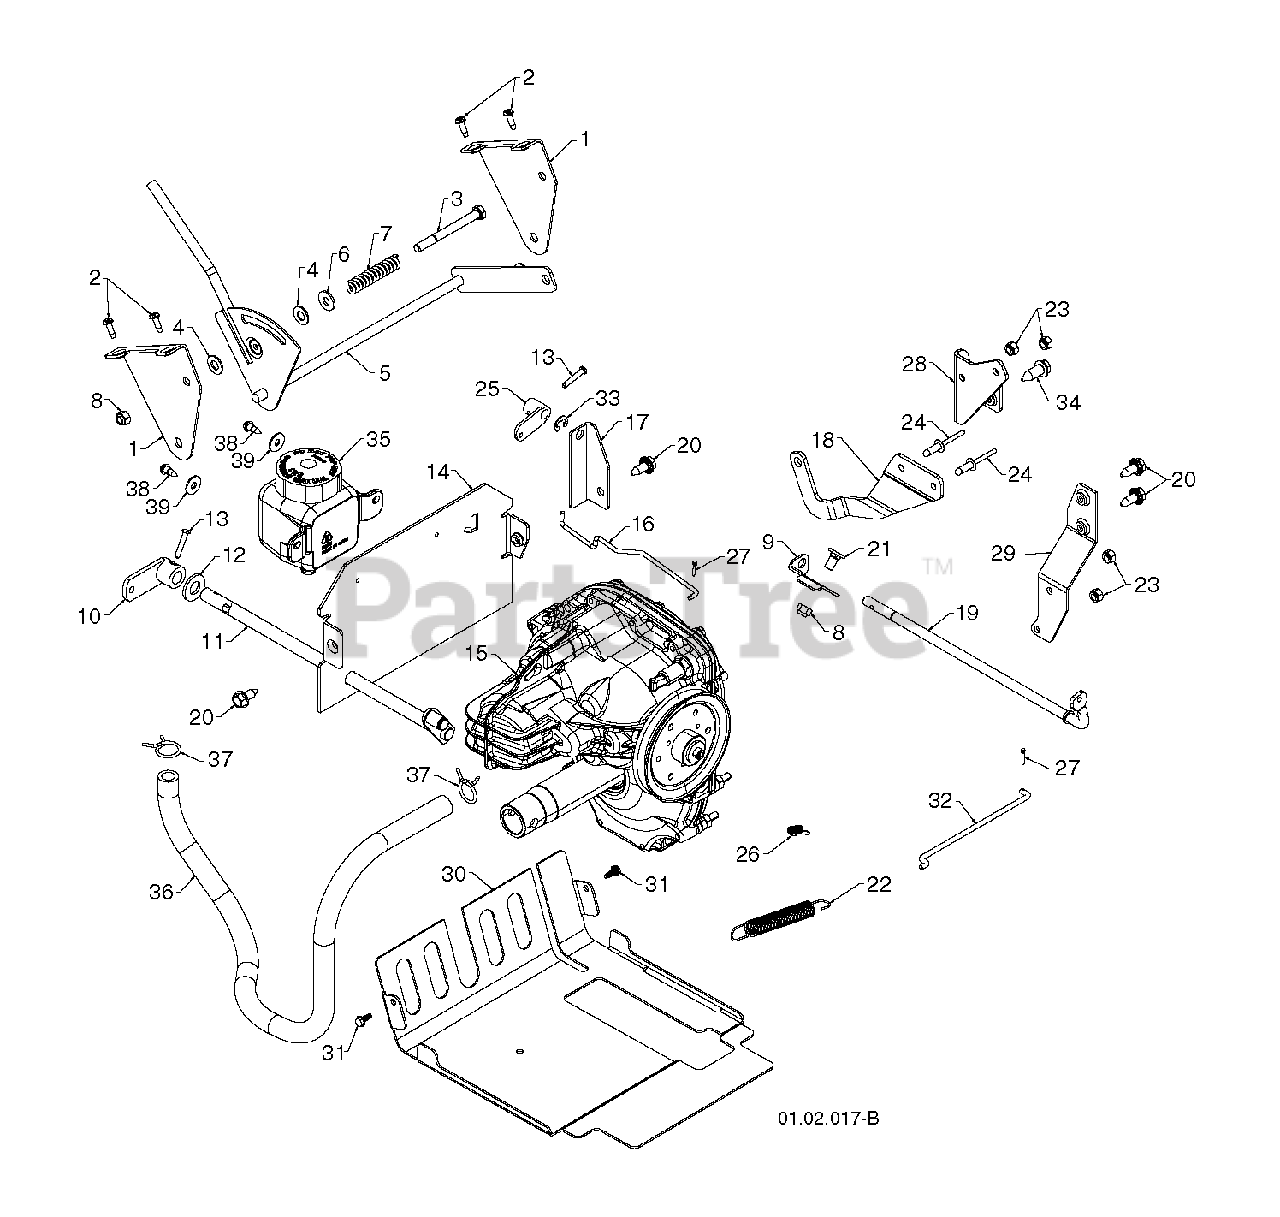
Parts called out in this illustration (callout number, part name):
1	BRACKET.SHIFT.HYDRO
2	SCREW #10-24 X 5/8
4	WASHER, NYLON FRICTION
5	LEVER ASSEMBLY, SPEED CONTROL
6	WASHER.20X8.5
7	SRPING.FRICTION.HYDRO
8	NUT.71038.31-18.HEX.NYLOCK
9	BRACKET.HYD.CLUTCH.
10	ARM.CONTRL.PIN.TRACK
11	CONTROL.SHAFT.ASM
12	WASHER.FLAT.1/2
13	CLEVIS PIN
14	PLATE.REAR.HYDRO.TRACK.ORANGE
15	TRANSMISSION
16	ROD, BYPASS VALVE
17	Clutch Bracket, Rear
18	ARM.CONTROL.HYDRO.SNOW
19	SHAFT.HYD.CLUTCH
20	BOLT.HEX.HD.WASHER.5/16-18X.75
21	BOLT.CARRIAGE.5/16-18X
22	SPRING, BRAKE
23	LOCKNUT.NYLOC.1/4-20
24	RIVET.POP.1/4X.475
25	ARM.HYD.CLUTCH
26	SPRING, TRACTION IDLER
27	RETAINER CLIP
28	BRACKET, ANTI-ROTATE
29	STRAP.TORQUE.HYDRO
30	COVER.TRANSMISSION.TRACK.BLACK
31	SCREW1032X.500
32	RP ROD.HYD.CLUTCH
33	E-RING.RETAINER.REINFORCED.375
34	SCREW 5/16-18X1
35	TANK.EXPANSION.350ML 71328
36	HOSE.EXPANSION.TANK.TRACK
37	CLAMP.SPRING.HOSE.795
38	SCREW.HEX.WASH.HD.TAPPING
39	BRACKET.EXPANS.TANK.TRACK.GREY
